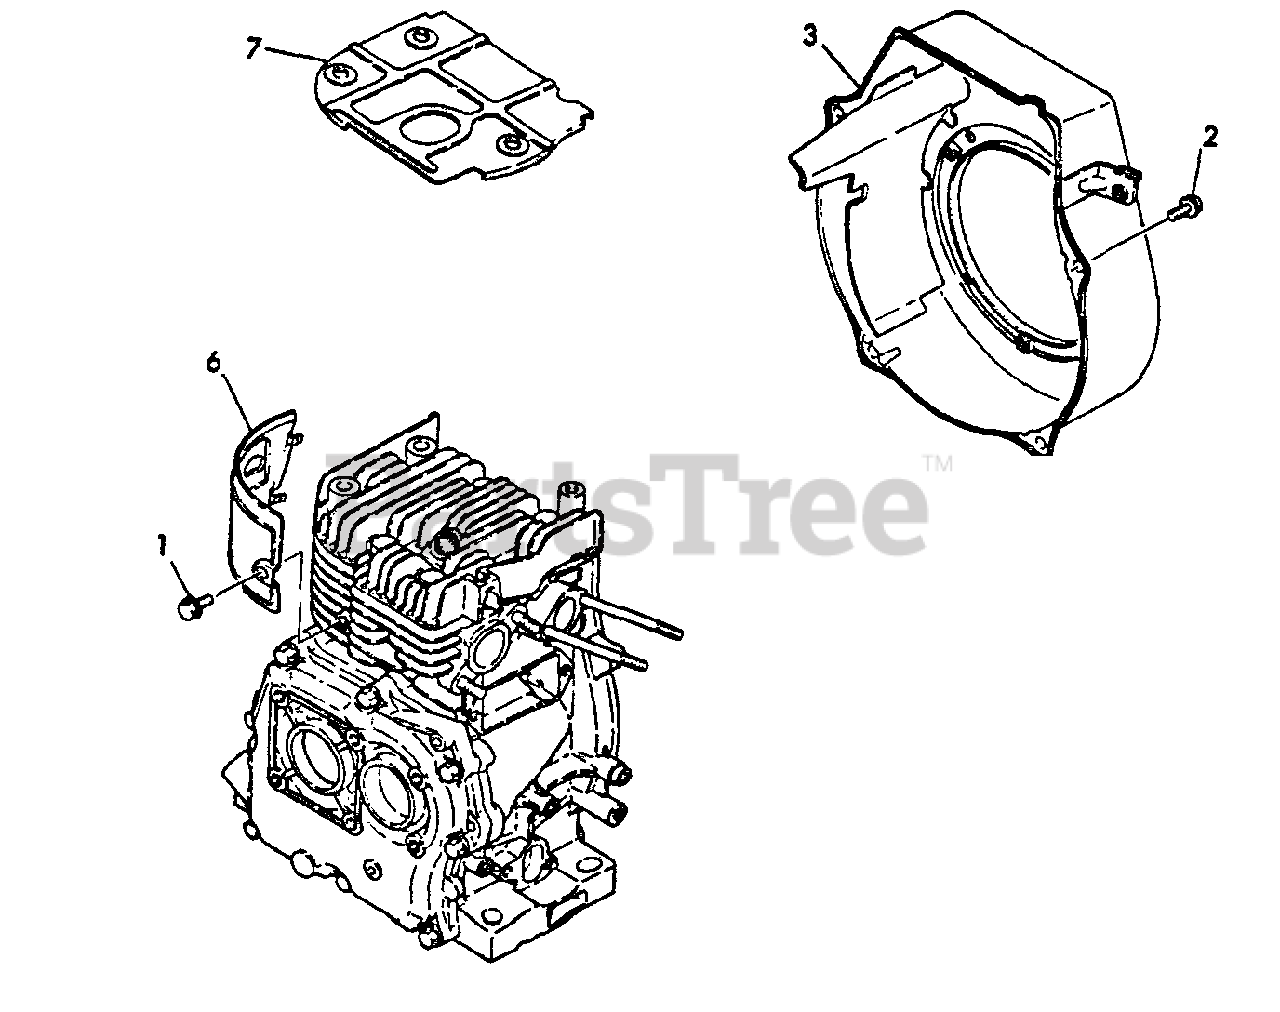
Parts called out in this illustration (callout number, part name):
1	BOLT - 6X8 -- PLATED
2	BOLT - 6X8 -- PLATED
3	COVER, FAN
6	PLATE
7	COVER, HEAD
